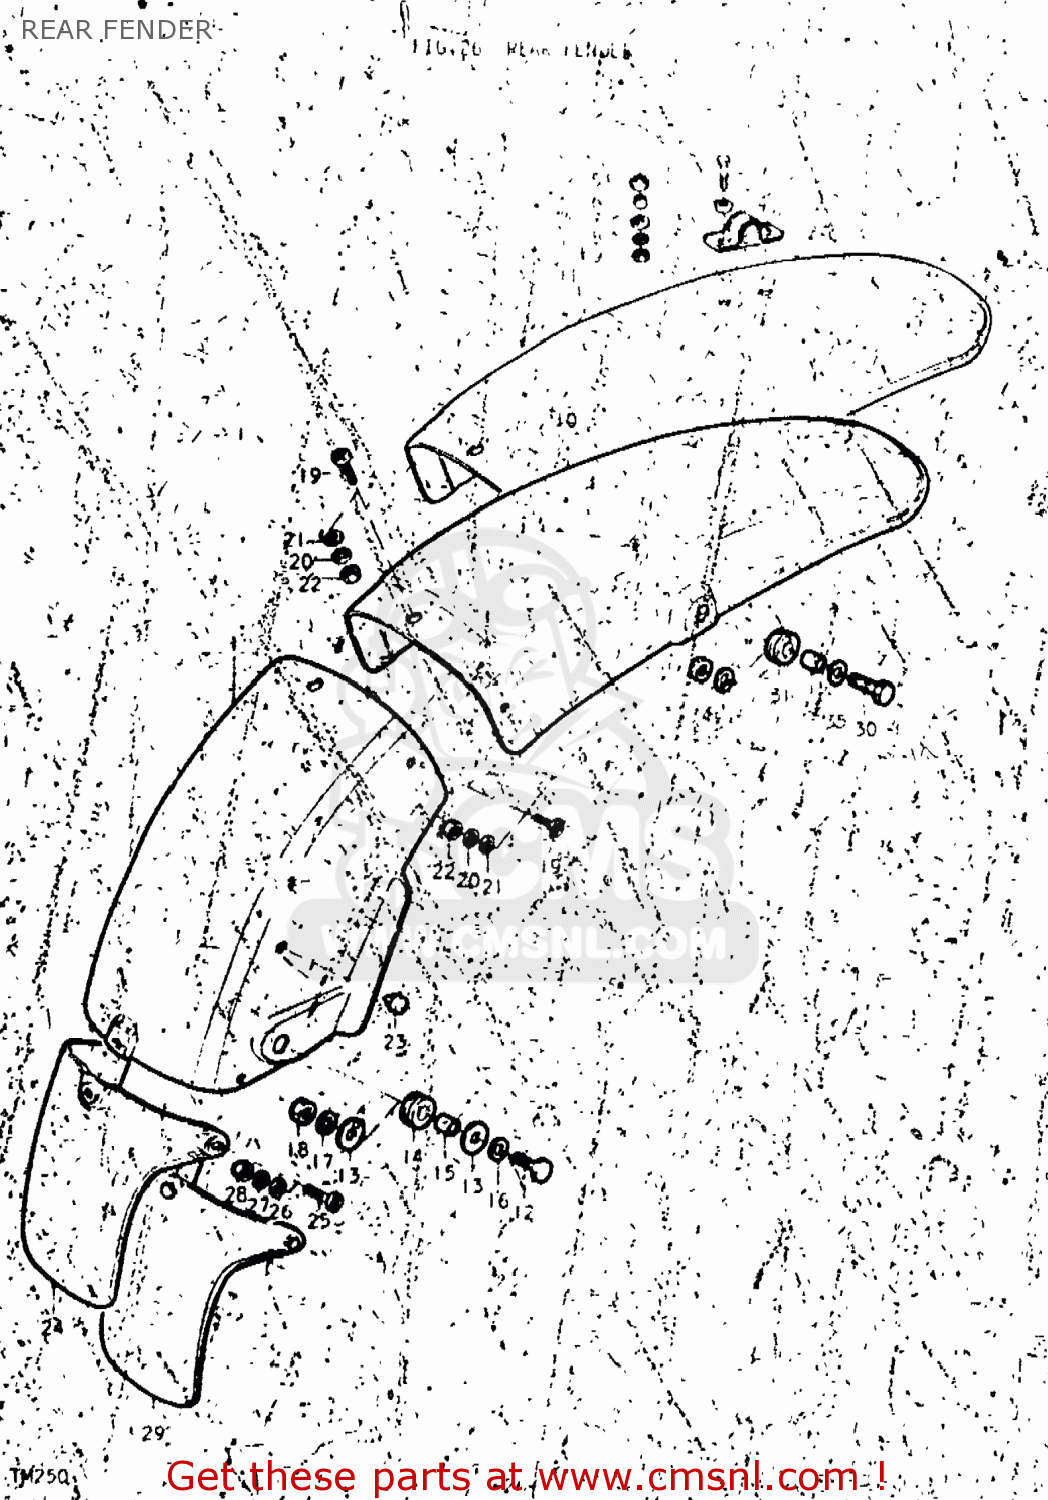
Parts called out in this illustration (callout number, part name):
1	FENDER,REAR
2	REINFORCEMENT,REAR FENDER
3	BOLT(6X18)
4	WASHER
5	CUSHION
6	SPACER
7	WASHER (6.5X20X1.2)
8	LOCK WASHER
9	NUT
10	FENDER,REAR
11	BODY, REAR FENDER REAR L,M
12	BOLT
13	WASHER (6.5X20X1.2)
14	CUSHION
15	SPACER(6.1X9X7.5)
16	WASHER
17	LOCK WASHER
18	NUT
19	SCREW
20	LOCK WASHER
21	WASHER
22	NUT
23	CUSHION
24	MUD GUARD,REAR FENDER
25	SCREW
26	LOCK WASHER
27	LOCK WASHER
28	NUT
29	MUD GUARD,REAR FENDER
30	BOLT
31	CUSHION
32	SPACER(6.1X9X7.5)
33	LOCK WASHER
34	NUT
35	WASHER (6.5X20X1.2)
